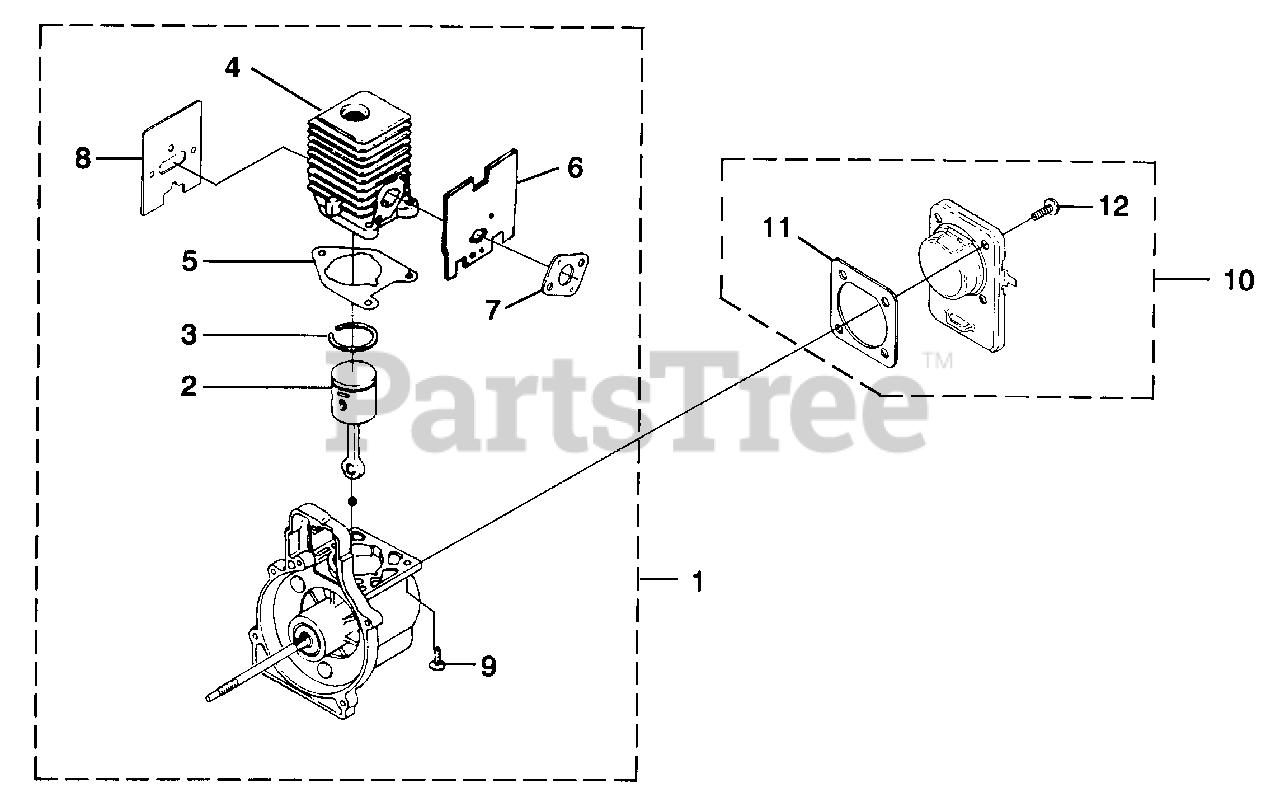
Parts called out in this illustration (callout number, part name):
1	SHORT BLOCK
2	PISTON & ROD ASSY.
3	RING-Piston
4	CYLINDER ASSY.
5	GASKET-Cylinder
6	GASKET-Heat Dam
7	GASKET-Carburetor
8	GASKET-Muffler
9	SCREW-Sems (12-24 X 3/4")
10	CRANKCASE COVER ASSEMBLY
11	GASKET-Crankcase Cover
12	SCREW-Sems (10-24 X 1/2")
